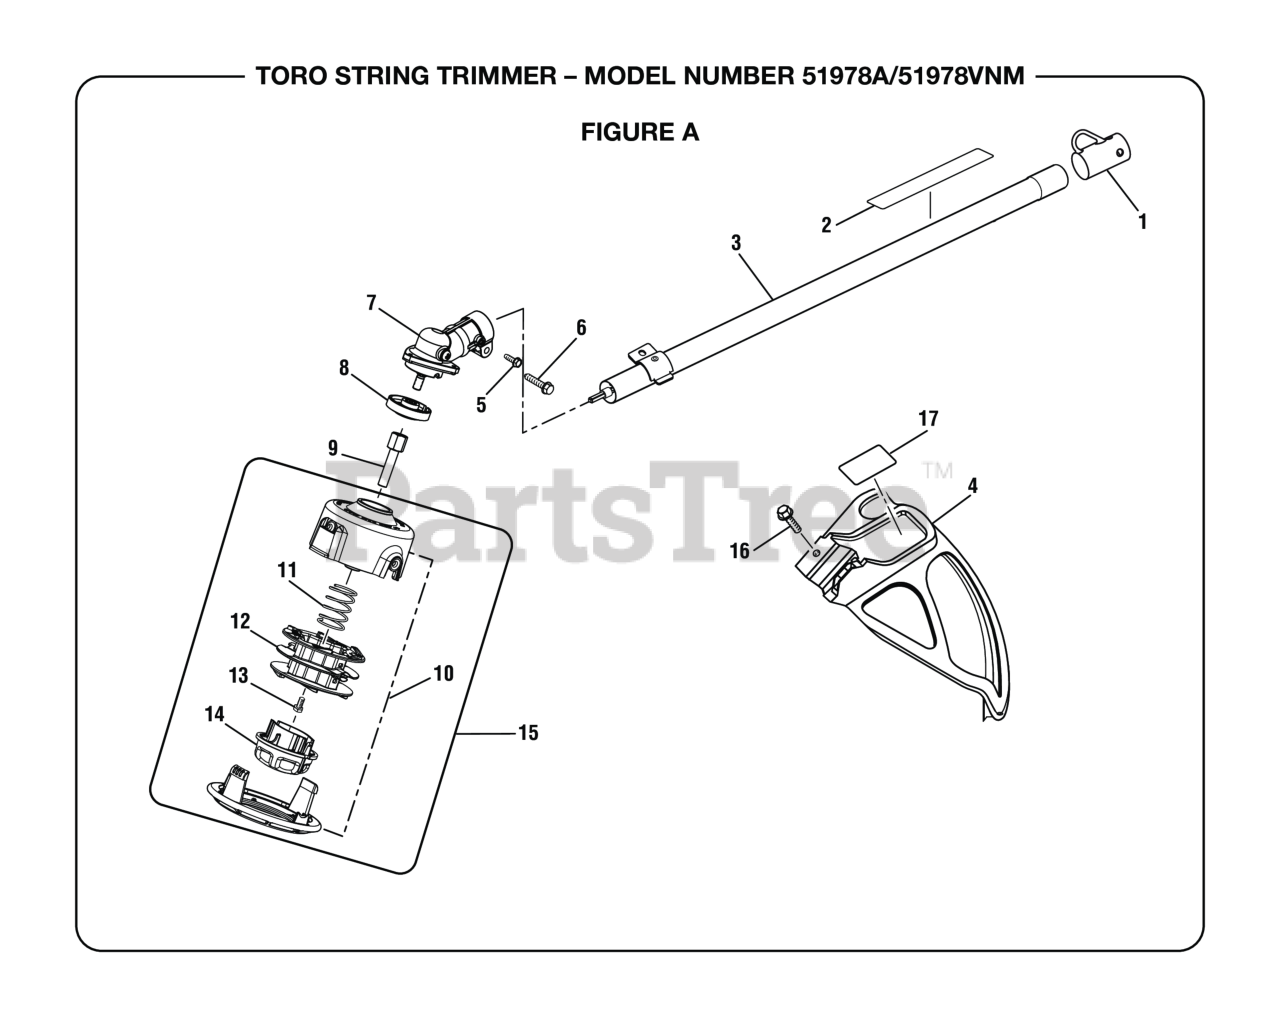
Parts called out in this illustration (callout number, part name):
1	Hanger Cap
2	Warning Icon Label
3	Straight Shaft Assembly
4	Grass Deflector Assembly
5	Screw w/Washer (10-24 x 5/8 in., Hex Hd. T.F.)
6	Screw (1/4-20 x 1-1/4 in., Hex Washer Hd. S.T.)
7	Gear Case Assembly
8	FLANGED WASHER
9	Trimmer Head Shaft Adaptor
10	Stringhead Housing
11	Compression Spring
12	Spool w/ Line (.095)
13	Screw (5/16 x 1/2 in., Left Hand)
14	Bump Knob
15	Trimmer Head Assembly (.095)
16	SCREW (#1/4-20 X 1-1/4 in. HEX WASHER HD.)
17	Grass Deflector Label
